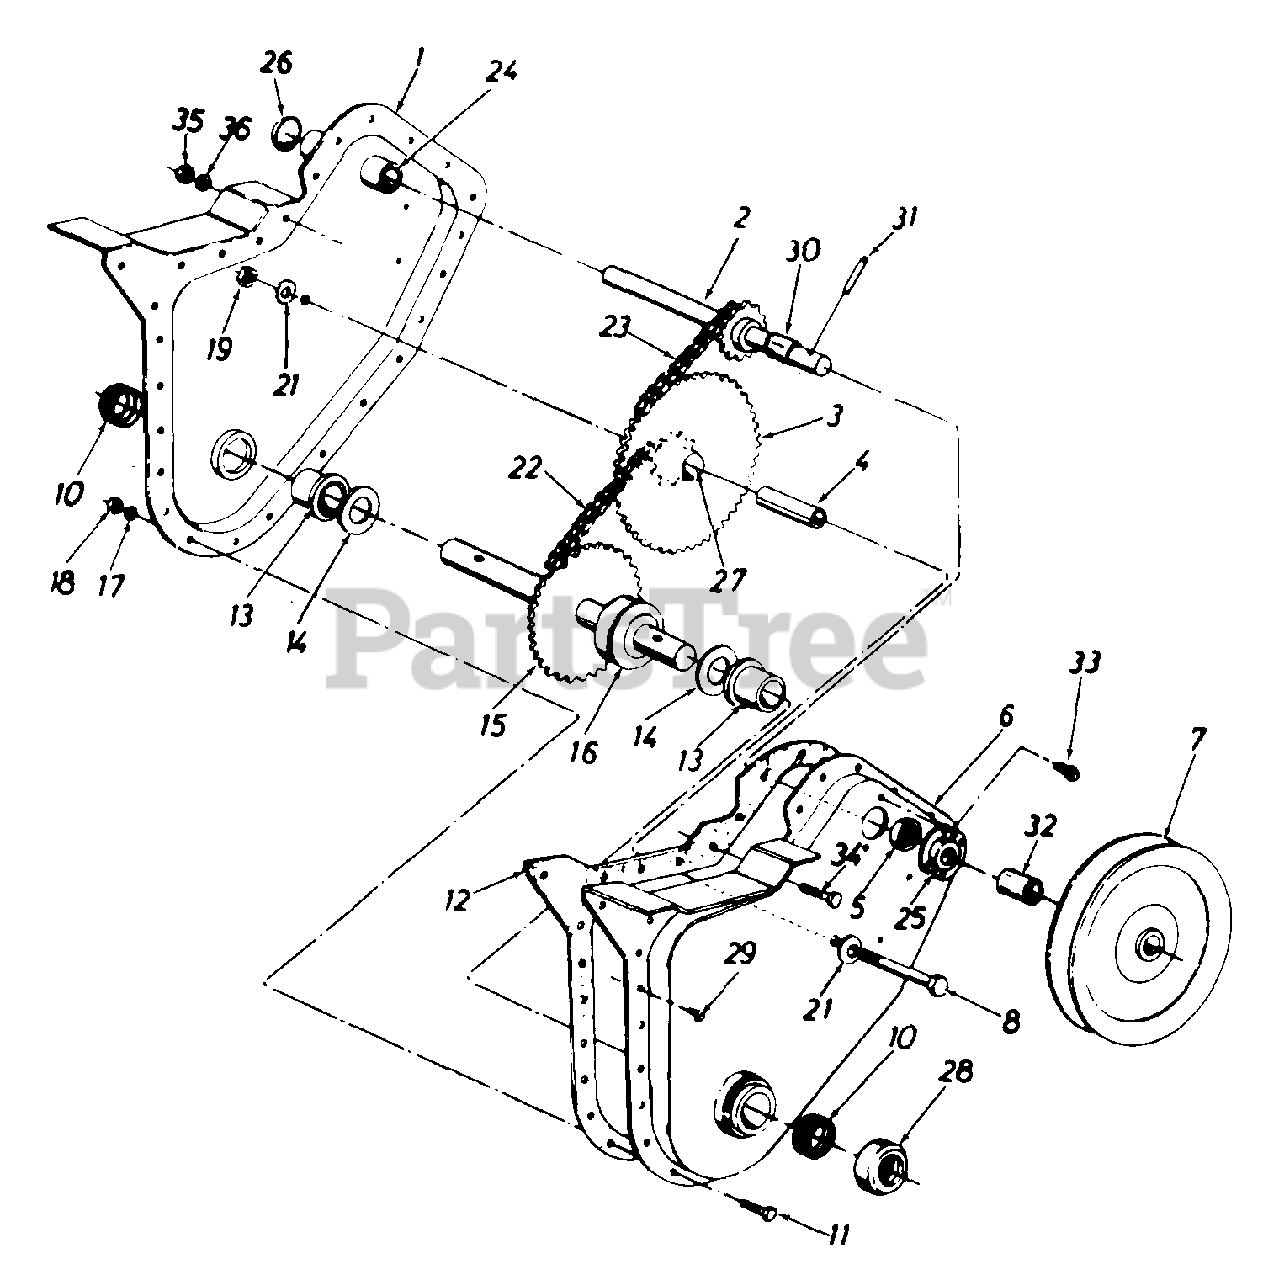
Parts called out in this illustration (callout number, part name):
1	Chain Case Ass'y.- R.H.
2	Input Shaft Ass'y.
3	Hub and Sprocket Ass'y.
4	Bearing Inner Race
5	Ball Bearing
8	Hex Bolt 3/8-24 x 2.5"
11	Hex Bolt 1/4-28 x .625"
12	Gasket
13	Flange Brg. .879" I.D.
14	Fl-Wash. .88" I.D. x 1.5"
15	Tine Shaft Ass'y.
16	Spacer 7/8" I.D.
17	L-Wash. 1/4" I.D.
18	Hex Nut 1/4-28 Thd.
19	Hex Ins. L-Nut 3/8-24 Thd.
21	Bell-Wash. .406" I.D.
22	Chain #420 1/2" Pitch 38 Links
23	Chain #35 .375" Pitch 50 Links
24	Bearing .62" I.D. x .813"
25	Bearing Housing
26	Expansion Plug 13/16" Dia.
27	Bearing
28	Dust Cap
29	Hex Wash. Hd. Self-Tap Scr. 1/4-20 x .50" Lg.
30	Spacer .63" I.D. x .77" O.D. x .38" Lg.
31	Spring Pin Spiral 1/4" Dia. x 1-1/2" Lg.
32	Spacer .647 x 1.25"
33	Hex Wash. Hd. Self-Tap Scr. 1/4-20 x .38" Lg.
34	Hex Bolt 5/16-18 x .75"
35	Hex Nut 5/16-18 Thd.
36	L-Wash. 5/16" I.D.
